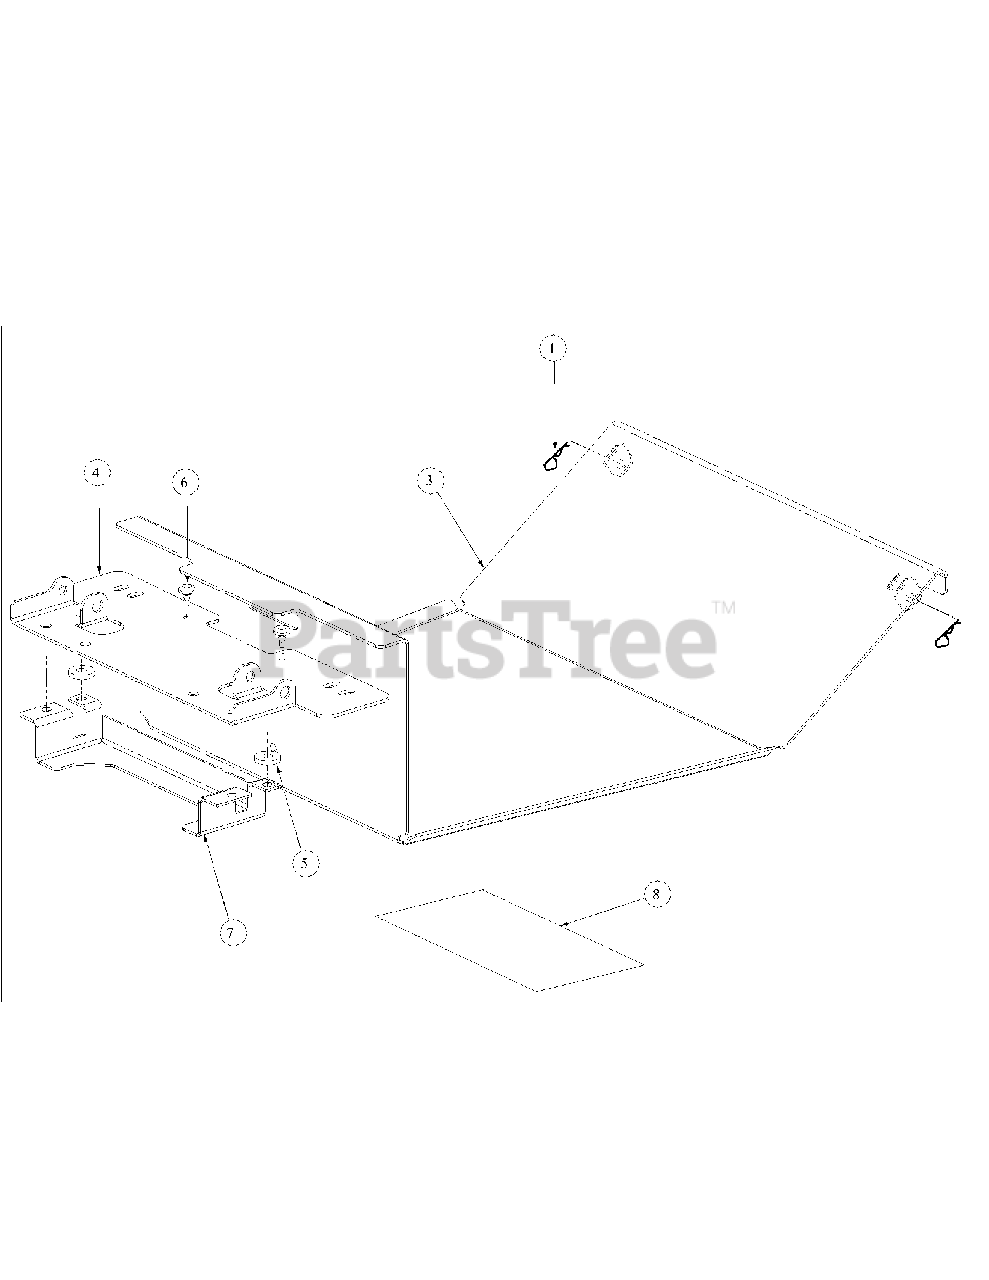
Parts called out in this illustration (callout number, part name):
1	Hair Pin, 3/8-1/2
3	Floor Panel Assembly
5	Washer
6	Rubber Bumper, .62 OD x .22 Thick
7	Support, Seat Bracket
8	Label, Belt Routing and Lubrication
